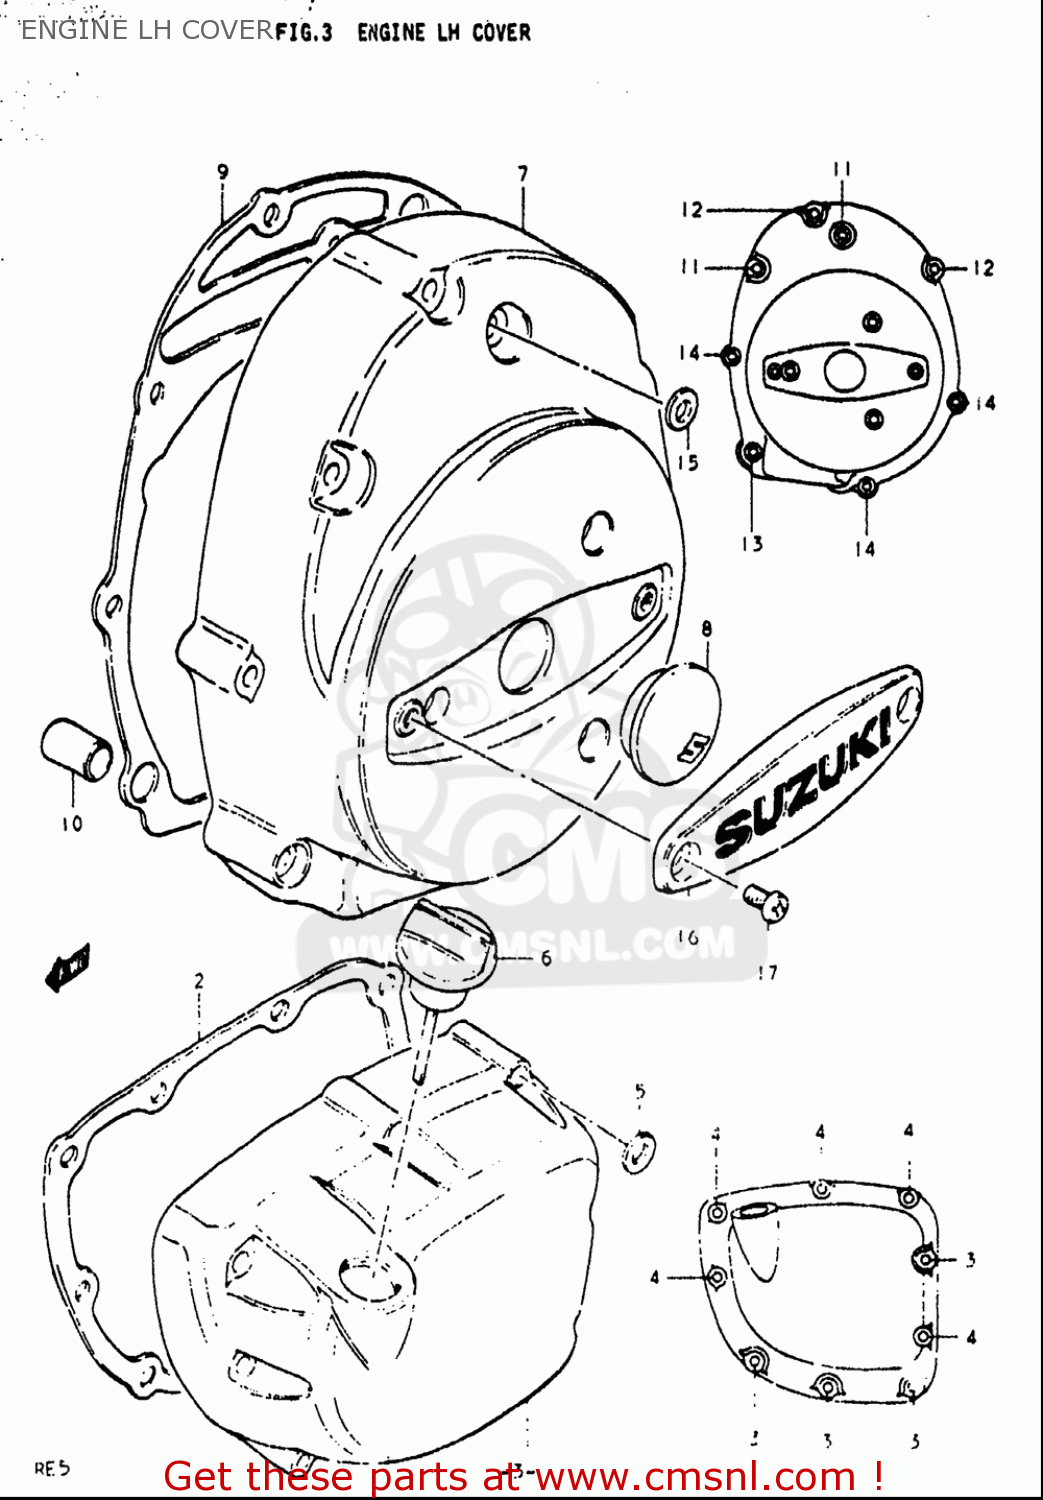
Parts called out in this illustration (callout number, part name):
5	WASHER
8	CAP(OD:32)
10	PIN
15	WASHER
17	SCREW
